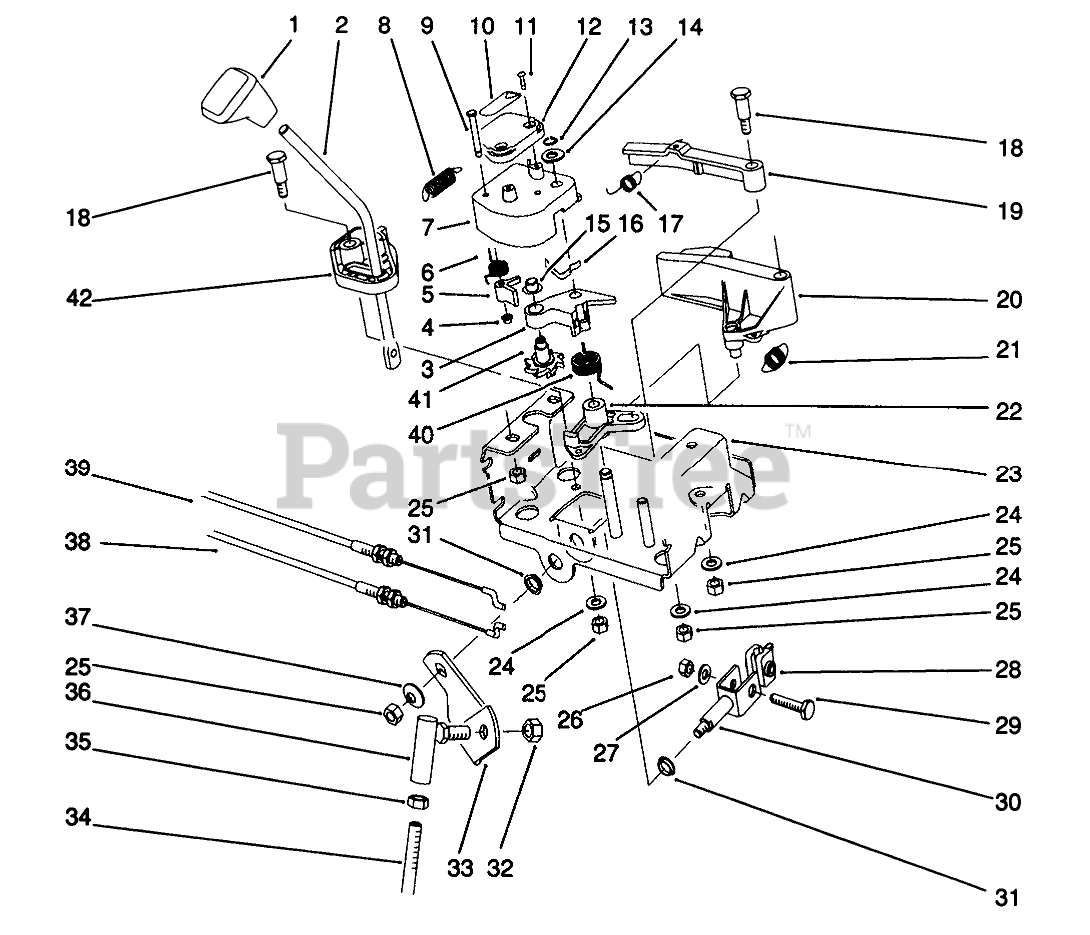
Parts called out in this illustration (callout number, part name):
1	KNOB-SHIFT
2	ROD-SHIFT
3	LEVER-WHEEL, INDEX
4	NUT-PUSH
5	TANG-INDEX
6	SPRING-TORSION
7	LATCH-LEVER
8	SPRING-EXTENSION
9	PIN-TANG
10	DECAL
11	SCREW-PPH
12	COVER-LATCH
13	RING-RETAINING
14	WASHER-THRUST
15	RETAINER-PUSH ON
16	SPRING-FLAT
17	SPRING-EXTENSION
18	SCREW-SHOULDER
19	LEVER-LOCKOUT
20	LEVER-REVERSE
21	SPRING-EXTENSION
22	LEVER-REVERSE, SWITCH
23	Frame-Control
24	WASHER-PLAIN
25	NUT-LOCK, NI
26	NUT-LOCK, NI
27	WASHER-FLAT
28	RETAINER-ROD, SHIFT
29	CAPSCREW
30	CLEVIS ASM
31	BUSHING
32	NUT-LOCK, NI
33	BRACKET-SHIFT
34	LOWER SHIFT ROD
35	NUT-HJ
36	JOINT-BALL
37	WASHER-BELLEVILLE
38	CABLE-GEARBOX
39	CABLE-ARM, LATCH
40	SPRING-TORSION
41	WHEEL-INDEX
42	BASE-LOCKOUT
